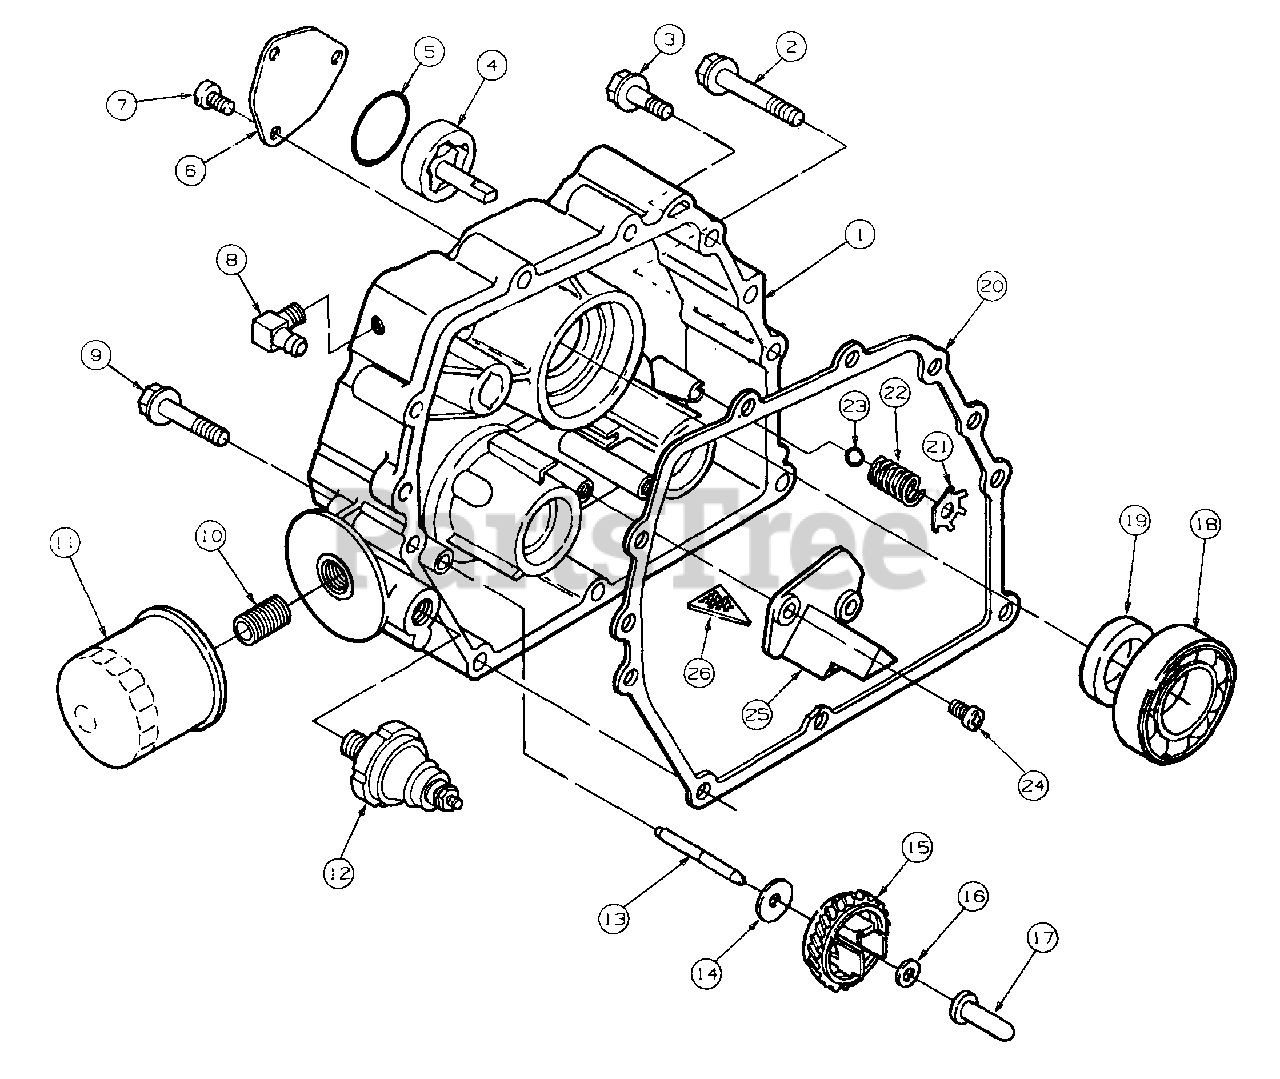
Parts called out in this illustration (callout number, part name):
2	Screw, Hex Head Flanged, Thread Forming, M8 x 1.25 x 70 mm
3	Screw, Hex Head Flanged, Thread Forming, M8 x 1.25 x 35 mm
4	Pump Assy, Oil
6	Cover, Oil Pump M6 x 1 x 14 mm
7	Screw, Pan Head Torx Drive
8	Elbow, Hose, 90°.
9	Screw, Hex Head Flanged, Thread Forming, M8 x 1.25 x 50 mm
10	Adapter, Oil Filter
12	Switch, Oil Pressure
13	Shaft, Governor
14	Washer, Flat, 6.2 mm ID x 18 mm OD x 1 mm Thk
15	Gear, Governor
16	Retainer, Governor Gear
17	Sleeve, Governor
18	Bearing, Crankshaft
19	Seal, Crankshaft Oil
20	Gasket, Gearcase
21	Ring, Retaining
22	Spring, Relief Valve
23	Ball, Steel, 5/16 OD
24	Screw, Torx Drive Pan Head, M6 x 1 x 14 mm
25	Tube, Oil Pickup
26	Screen, Oil Pickup
